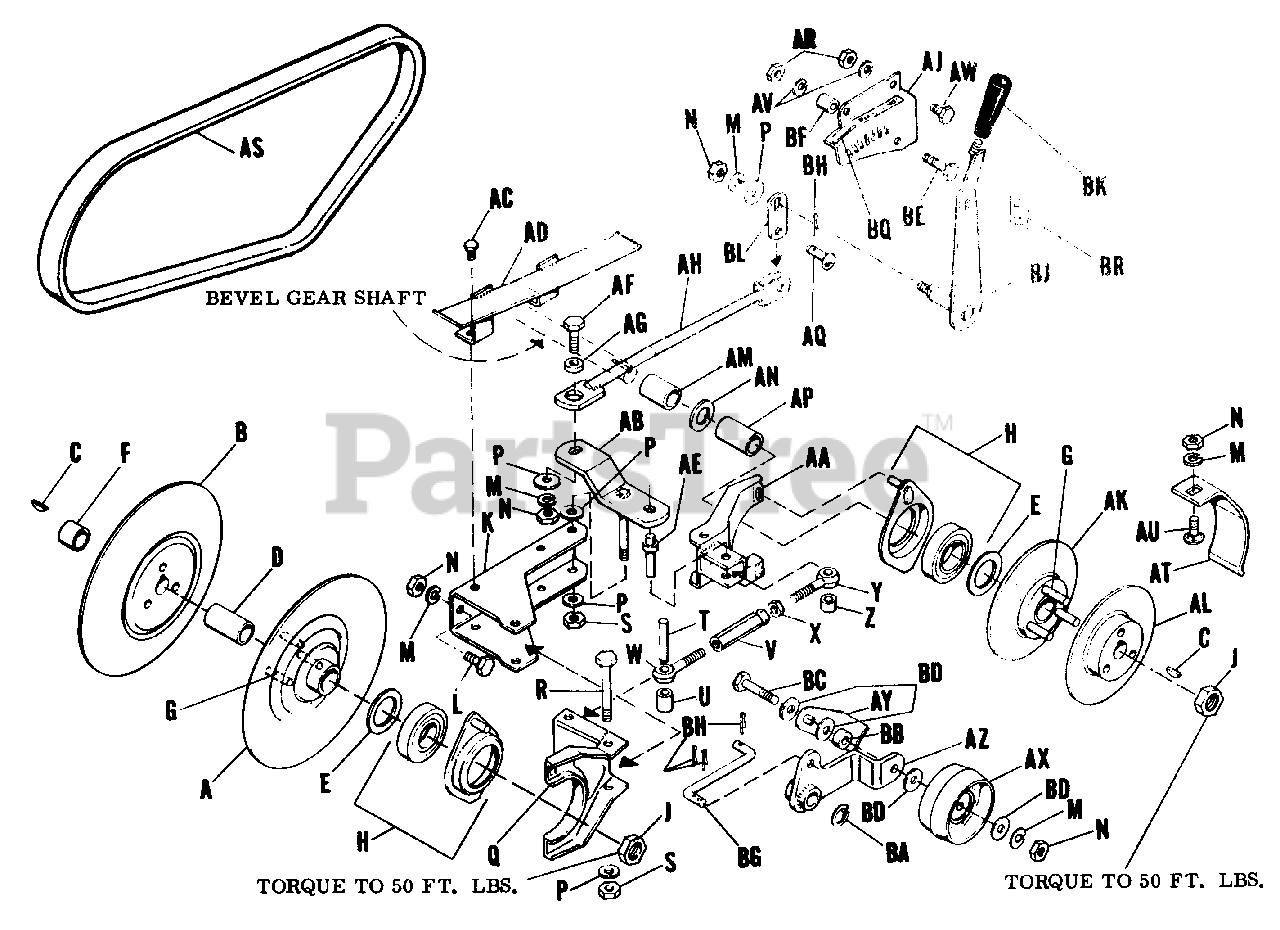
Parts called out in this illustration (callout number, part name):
A	Pulley-Half Assembly
B	Pulley-Half
D	Driven Slide Spacer (Teflon Coated)
H	Retainer Ring/Bearing Assembly
J	Hex Jam Nut, Lock
K	Variable Speed Bracket
L	Hex Capscrew, 3/8"-16 x 7/8" lg.
M	Lock Washer, 3/8"
N	Hex Nut, 3/8"-16
P	Plain Washer, 3/8"
Q	Transmission Fork Assembly
R	Special Screw
S	Hex Nut, 3/8"-16 Lock
T	Pivot Pin
V	Turnbuckle Body
W	Eyebolt, R.H.
X	Hex Nut, 3/8"-24
Y	Eyebolt, L.H.
AA	Bevel Gear Housing Fork Assy.
AB	Fork, Rocker Assy.
AC	Screw, Taptite, 1/4"-20 x 5/8"
AD	Belt Guard Assembly
AF	Hex Capscrew, 3/8"-16 x 1-1/4" lg.
AH	Arm Assembly
AK	Pulley-Half Assembly
AL	Pulley Half
AM	Slide Spacer
AN	Stop Washer
AP	Slide Spacer (Teflon Coated)
AR	Hex Nut, 5/16"-18
AS	BELT, HI, 54"
AT	Belt Guard
AU	Carriage Bolt, 3/8"-16 x 3/4" lg.
AV	Lock Washer, 5/16"
AW	Hex Capscrew, 5/16"-18 x 5/8" lg.
AX	Idler Pulley
AY	Idler Belt Stop
AZ	Idler Lever Assembly
BA	Retaining Ring
BC	Hex Capscrew, 3/8"-16 x 2" lg.
BD	Plain Washer, 3/8"
BE	Hex Capscrew, 5/16"-18 x 1-1/2" lg.
BG	Clutch Link
BH	Cotter Pin
BJ	Lever Assembly
BM	Film Quardrant
BN	Film Instruction
